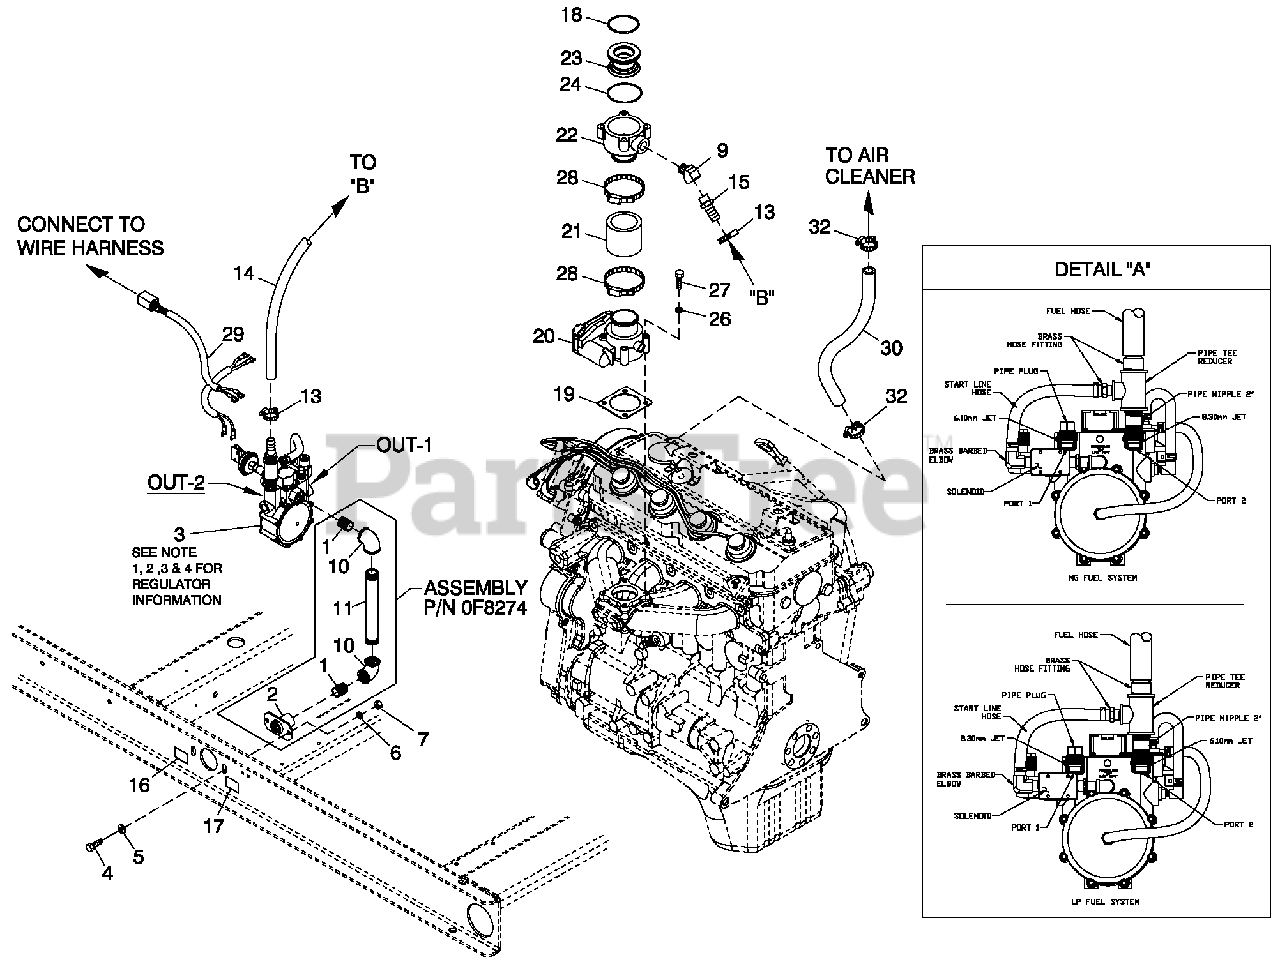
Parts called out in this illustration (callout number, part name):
1	NIPPLE CLOSE 3/4X1.375
2	FLANGElFUELlINLETl
3	REGULATOR ASSY 2.4L (25KW)
4	SCREW HHC M8-1.25X 20 G8.8
5	WASHER FLAT 5/16-M8 ZINC
6	WASHER LOCK M8-5/16
7	NUTlHEXlM8-1.25lG8lCLEARlZINCl
9	STREETlELl45Dl1/2lNPTlBRASSl
10	ELBO l90Dl3/4lNPTl
11	NIPPLElPIPEl3/4lNPTlXl7l
13	CLAMP HOSE #10 .56-1.06
14	HOSE 3/4 ID SAE-30R2 (18" LG)
15	BARBEDlSTRl1/2lNPTlXl3/4l
16	DECALlINLETlPRESSUREl
17	DECALlFUELlINLETlNGl(NATURALlGASlAPPLICATION)
18	O-RINGl45.63lIDlXl2.62l IDTHl
19	GASKETlBOSCHl32l
20	ACTUATORlBOSCHl40lGOVERNORl(45K )l
21	HOSElCOOLl2lINlIDl20R4l(45K )l
22	MIXERlACTUATORl32MMlMACHINEDl(25K )l
23	VENTURIlTHROTTLEl26MMl(35l&l45K )l
24	O-RINGl47.625lIDlXl2.38l IDTHl
26	WASHER LOCK M6-1/4
27	SCREW SHC M6-1.0 X 45 G12.9
28	CLAMPlHOSEl#28l1.32-2.25l
29	HARNESS CPL FUEL JUMPER
30	HOSEl3/8lIDlSINGLElBRAIDl(18"lLG)l
32	CLAMPlHOSEl#10l.56-1.06l
